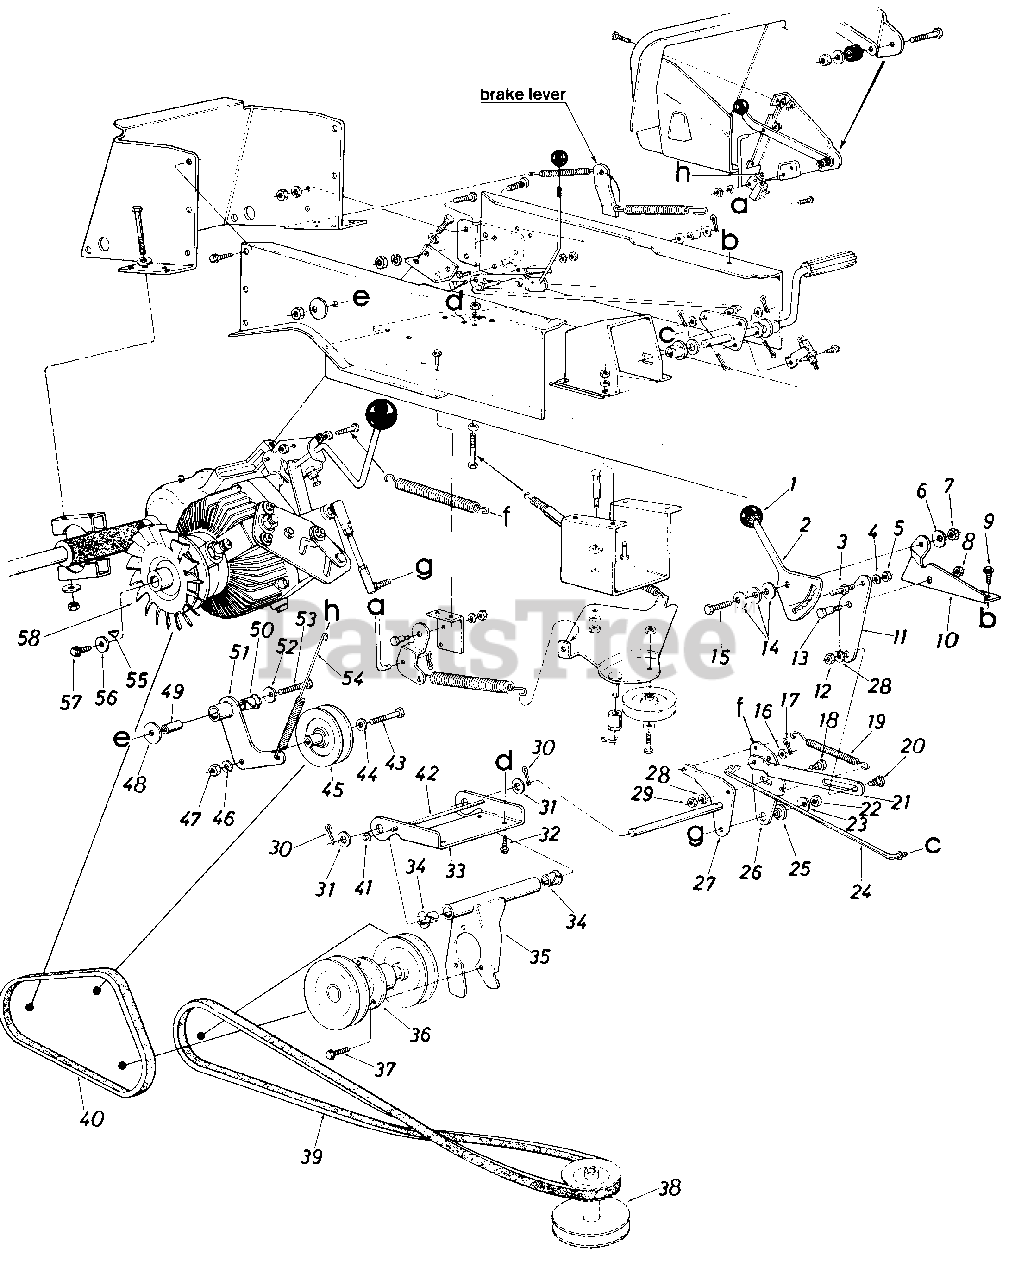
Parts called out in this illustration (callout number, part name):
1	Gear Shift Knob
2	Speed Selector Cam
3	Hex Stud .250" Dia. x .62"
4	L-Wash. 1/4" I.D.
5	Hex Nut 1/4-20 Thd.*
6	Bell-Wash. .400" I.D. x 1.13" O.D.
7	Hex Ins. L-Nut 3/8-24 Thd.
8	Hex Top L-Nut 3/8-16 Thd.
9	Hex Wash. Hd. S-Tap Scr. 1/4-20 x .751' Lg.
10	Speed Selector Mtg. Brkt.
11	Speed Selector Transfer Brkt.
12	Hex Nut 5/16-18 Thd.
13	Shld. Bolt .500" Dia. x .170
14	Bell-Wash. .39" I.D. x 1.13" O.D.
15	Hex Bolt 3/8-24 x 1.00" Lg.
16	Fl-Wash. .385" I.D. x .87" O.D.
17	Cotter Pin 3/32" Dia. x .75" Lg.
18	Shld. Bolt .437" Dia. x .180
19	Extension Spring .50" Dia. x 2.75" Lg.
20	Shld. Bolt .437" Dia. x .180
21	Speed Selector Link
22	Hex Nut 3/8-24 Thd.*
23	Bell-Wash .39" I.D. x 1.13" O.D.
24	Rod-Speed Control .312" Dia.
25	Shld. Spacer .625" I.D.
26	Speed Cont. Transfer Swivel Brkt.
27	Speed Control Transfer Ass'y.
28	L-Wash. 5/16" I.D.
29	Hex Nut 5/16-18 Thd.
30	Cotter Pin 1/8" Dia. x 1.00" Lg.*
31	Fl-Wash. .640" I.D. x 1.24" O.D.
32	Hex Wash S-Tap Scr. 1/4-20 x .50" Lg.
33	Idler Mtg. Brkt.
34	Flanged Nyliner Brg. .376 I.D. x .437
35	Mounting Brkt. Ass'y.
36	Jack Shaft Ass'y.
37	Hex Sems Bolt 5/16-18 x .75" Lg.
38	Engine Pulley 47.5" I.D. x 5.56" O.D.
39	"V"-Belt 1/2 x 59.0 Lg.
40	"V"-Belt 1/2" x 32.0" Lg.
41	Push Cap
42	Rod-3/16" Dia. x 7.12" Lg.
43	Hex Bolt 3/8-24 x 1.50" Lg.
44	Fl-Wash. .385" I.D. x .87" O.D.
45	Idler Pulley 4.0" O.D. x 5l8"-"V"
46	L-Wash. 3/8" I.D.
47	Hex Nut 3/8-24 Thd.*
48	Bell-Wash. .40" I.D. x .87" O.D.
49	Spacer.38" I.D. x .62" O.D. x 1.87" Lg.
50	Flanged Nyliner Brg.
51	Idler Pivot Brkt. Ass'y.
52	Fl-Wash. .38" I.D. x .87" O.D.
53	Hex Bolt 3/8-24 x 2.00" Lg.
54	Extension Spring .56" O.D. x 7.75" Lg.
55	#9 Hi-Pro Key .316" x .75" Dia.
56	Fl-Wash. .505" I.D. x 1.0" O.D.
57	Hex Wash. Hd. S-Tap Scr. 1/4-20 x .75" Lg.
58	Trans. Pulley & Fan Ass'y.
